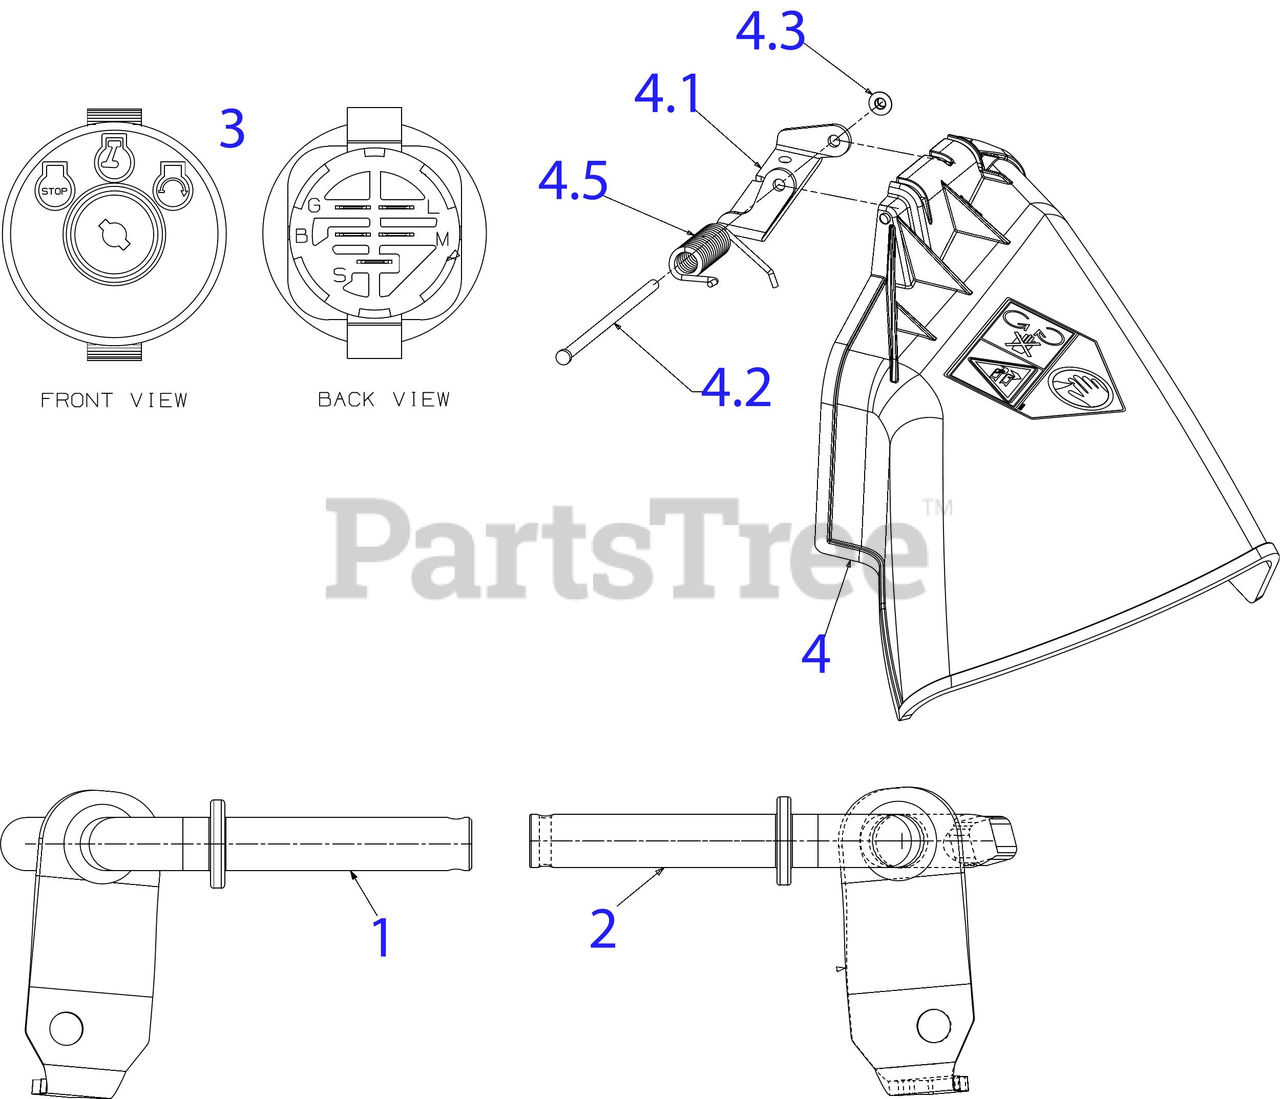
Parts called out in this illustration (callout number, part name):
1	FRONT AXLE ASSEMBLY (LH)
2	FRONT AXLE ASSEMBLY (RH)
3	3 POSITION KEY SWITCH
4	CHUTE ASSEMBLY
4.1	HINGE MOUNTING BRACKET
4.2	HINGE PIN
4.3	PUSH NUT
4.5	TORSION SPRING
